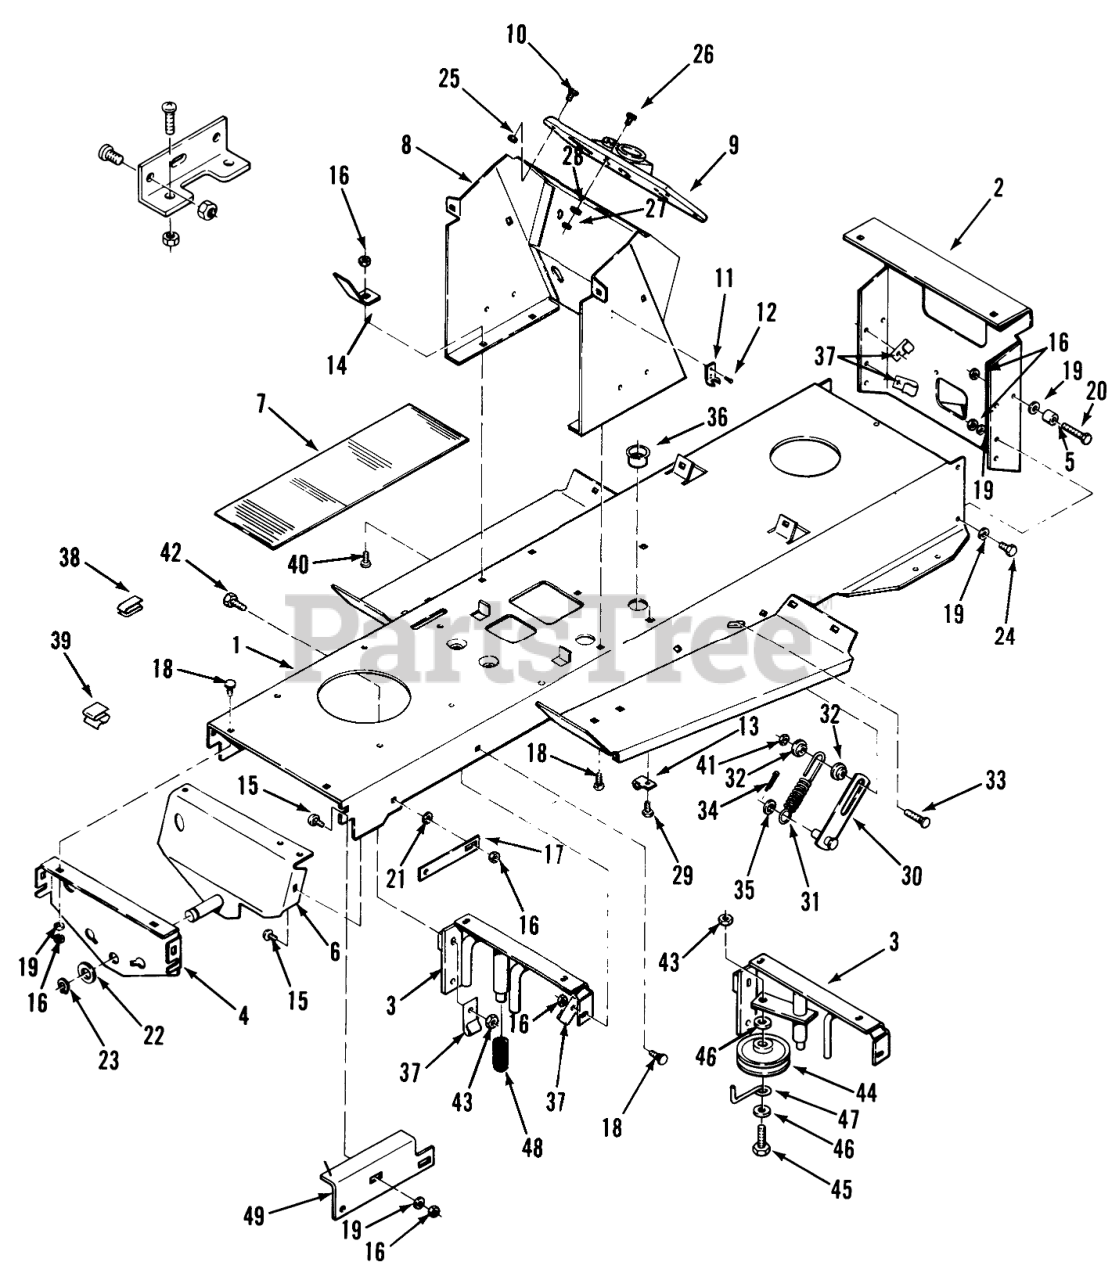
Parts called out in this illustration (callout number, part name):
1	Frame
2	PLATE-DRAWBAR R
3	ASS'Y-FRAME SUPPO R
4	PLATE SUPT - AXLE R
5	BEARING-CAM ROLLER
6	ASS'Y-AXLE SPT RE R
7	PAD-FOOTREST
8	HOODSTAND ASSY B
9	CONSOLE
10	SCREW #10X.62 PHCR
11	KEEPER-LATCH
12	POPRIVET 1/8X 1/8 BK
13	J-CLIP
14	BRACKET FUSE
15	SCREW-CARR
16	NUT-LOCK, NI
17	STRAP R
18	Bolt
19	WASHER-PLAIN
20	SCREW-HH
21	Washer-Lock
22	WASHER
23	RING-RETAINING
24	SCREW-HH
25	Nut
26	Screw
27	NUT-HEX
28	WASHER-LOCK
29	Bolt
30	ASSY LINK B
31	SPRING
32	BUSHING
33	Bolt-Carriage
34	PIN-COTTER
35	WASHER
36	BUSHING-NYLON 1.093
37	CLIP
38	RETAINER
39	SPEED CLIP
40	Bolt
41	Nut
42	SCREW-HH
43	NUT-LOCK, NI
44	IDLER PULLEY R
45	SCREW-HH
46	WASHER-FLAT
47	RETAINER BELT R
49	BRACKET R.H. R
